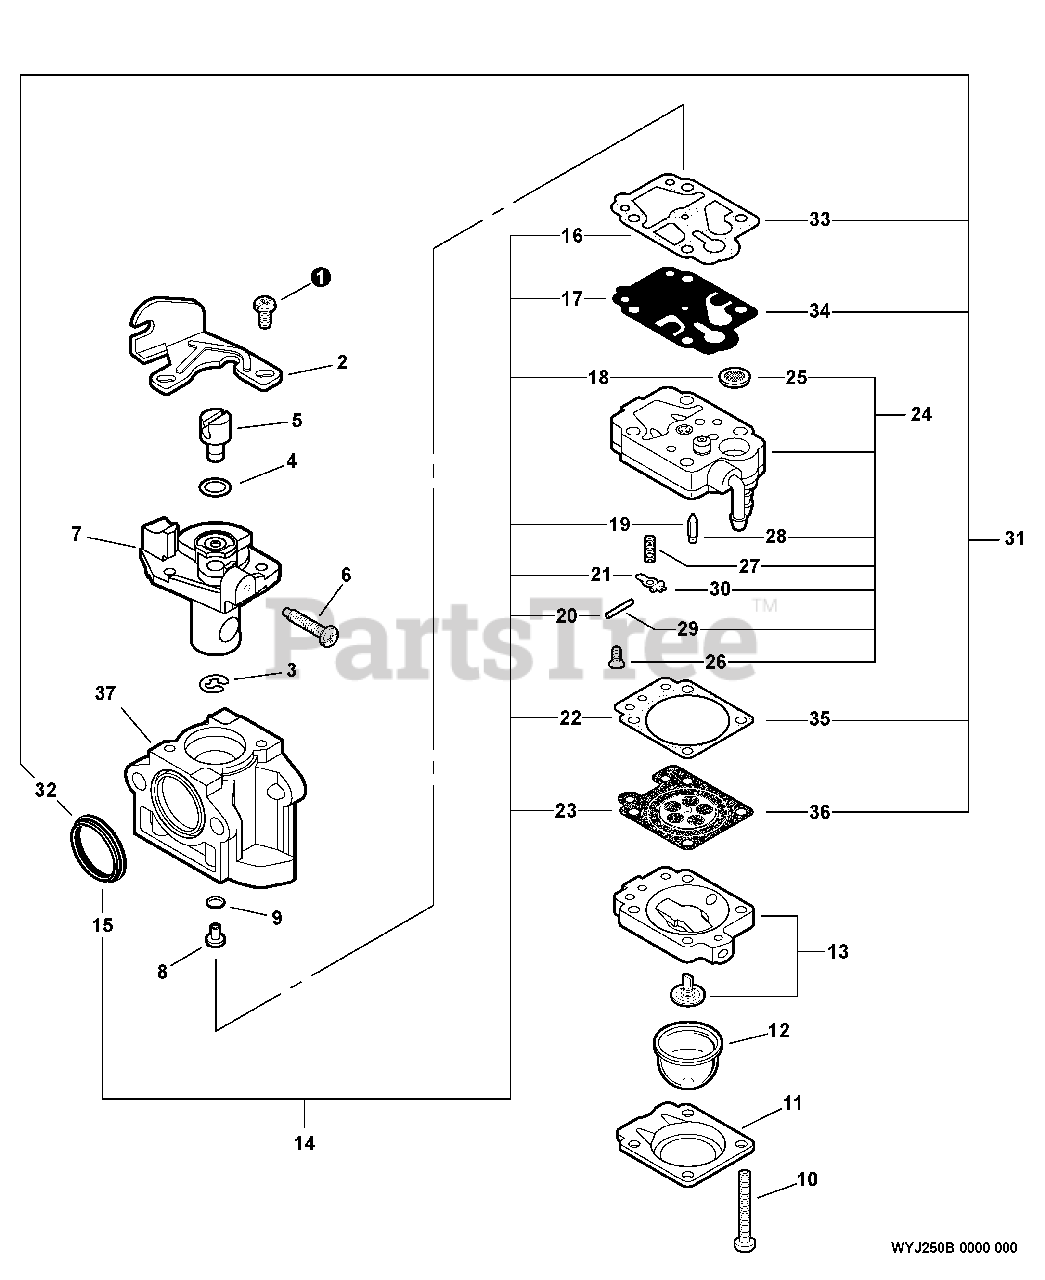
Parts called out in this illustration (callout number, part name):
2	BRACKET, THROTTLE CABLE
7	THROTTLE VALVE ASSY
8	JET, MAIN
11	RETAINER, PURGE BULB
12	BULB, PURGE
13	BODY ASSY, PURGE
14	REPAIR KIT, CARBURETOR
15	SEAL
16	GASKET, PUMP
17	DIAPHRAGM, PUMP
18	STRAINER
19	VALVE, INLET NEEDLE
20	PIN, METERING LEVER
21	LEVER, METERING
22	GASKET, DIAPHRAGM
23	DIAPHRAGM, METERING
24	BODY ASSY, PUMP
25	STRAINER
27	SPRING, METERING LEVER
28	VALVE, INLET NEEDLE
29	PIN, METERING LEVER
30	LEVER, METERING
31	GASKET / DIAPHRAGM KIT
32	SEAL
33	GASKET, PUMP
34	DIAPHRAGM, PUMP
35	GASKET, DIAPHRAGM
36	DIAPHRAGM, METERING
37	BODY, CARBURETOR
